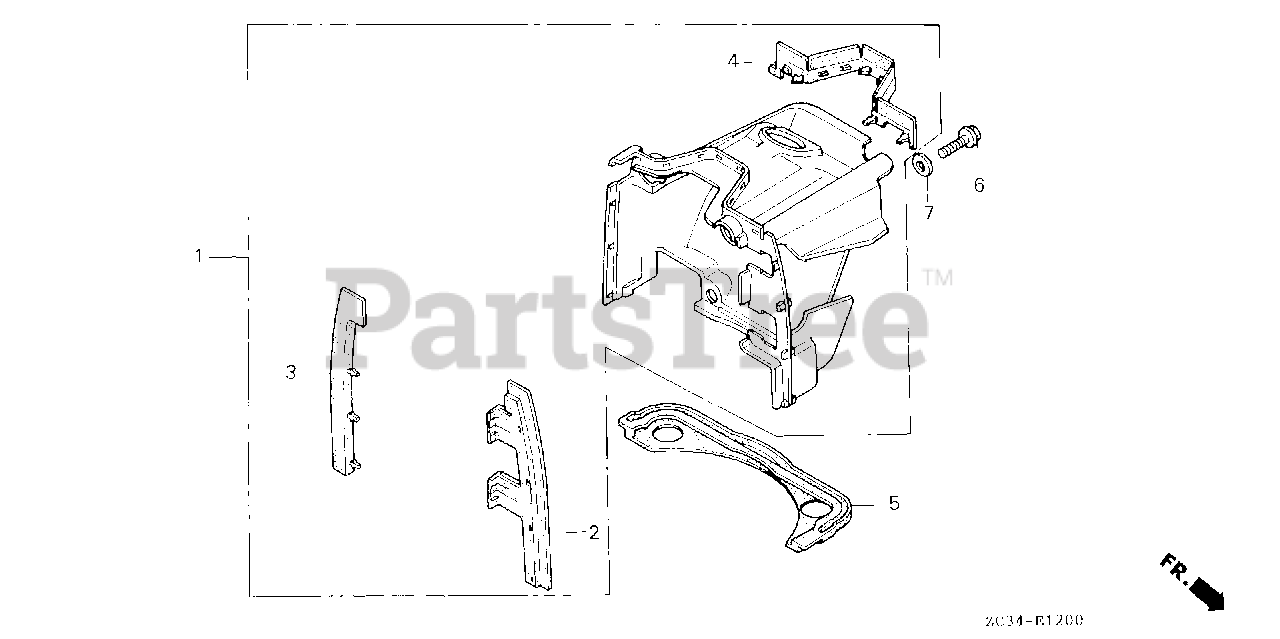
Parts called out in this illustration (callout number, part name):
1	SHROUD ASSY.
2	R. RUBBER, SHROUD SEALING
3	L. RUBBER, SHROUD SEALING
4	RUBBER, SHROUD SEALING (UPPER)
5	RUBBER, GENERATOR SEALING
6	BOLT, FLANGE (5X10)
7	WASHER, PLAIN (5MM)
